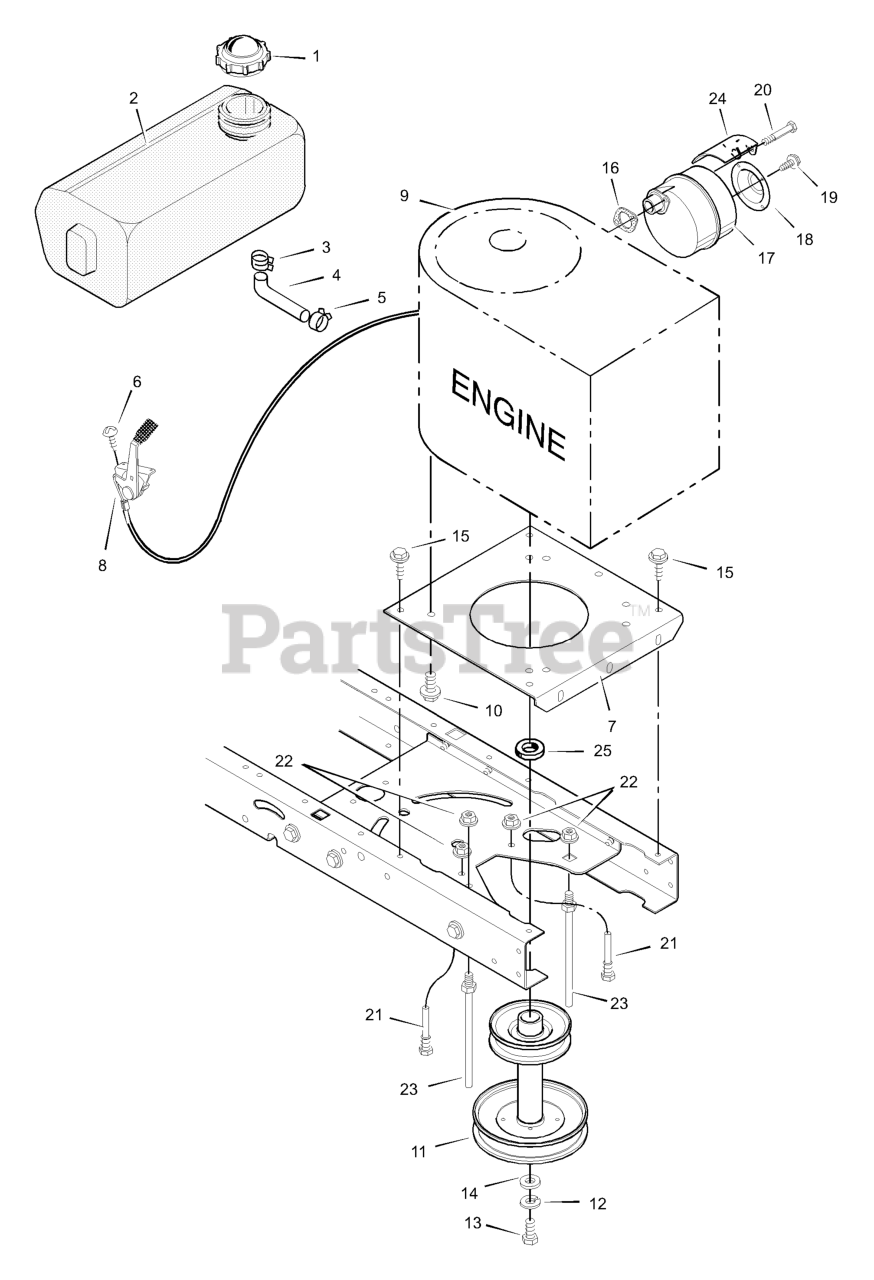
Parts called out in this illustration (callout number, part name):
1	Fuel Cap
2	Fuel Tank
3	Hose Clamp
4	Fuel Line
5	Hose Clamp
7	Plate, Engine
8	Throttle Control
9	Engine
10	Bolt, Engine Mount
11	STACK PULLEY ASSEMBLY
12	Lockwasher
13	Bolt, Hex
16	GASKET, Exhaust
17	Muffler
18	Deflector, Muffler
20	Bolt, Hex
21	Guide, Belt
22	Nut, Flange
23	Guide, Belt
24	Shield, Heat
